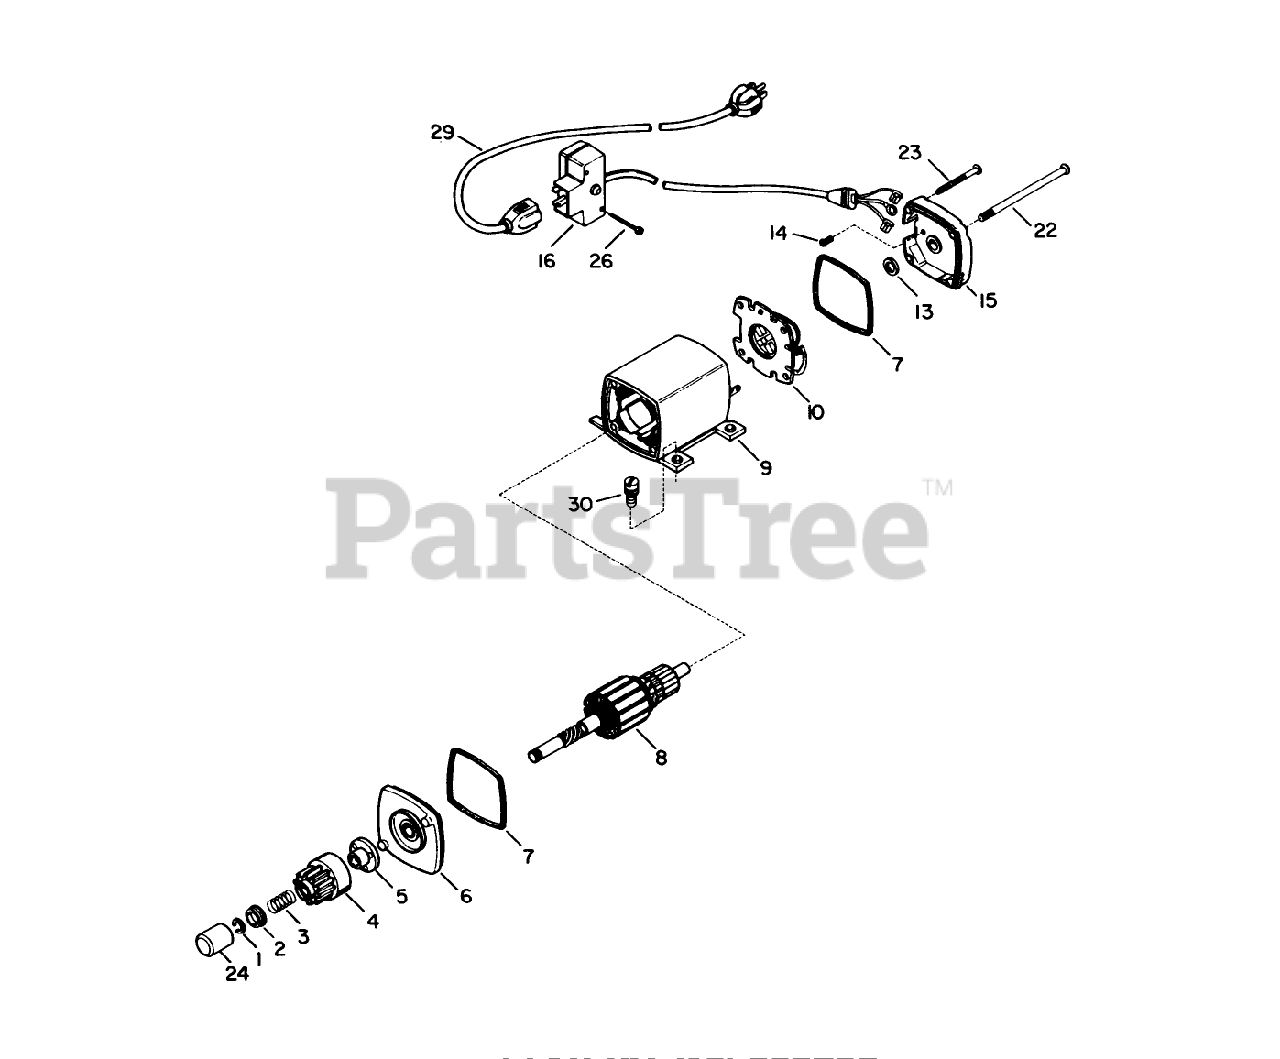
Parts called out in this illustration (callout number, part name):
1	Ring-Retainer
2	Retainer-Spring
3	Spring-Anti Drift
4	Gear
5	Nut-Engaging
6	Cap Assembly-Cap End (Incl. Ref. #7)
7	O-Ring
8	Armature
9	Housing ASM
10	Card ASM
13	Washer-Thrust
14	Screw-Ground
15	Cap Assembly (Incl. Ref. #7)
16	Box Assembly-Switch (Incl. Ref. #26)
22	Bolt-Case
23	Screw-Ground
24	Cover-Dust
26	Screw
29	Cord-Extension
30	Screw
